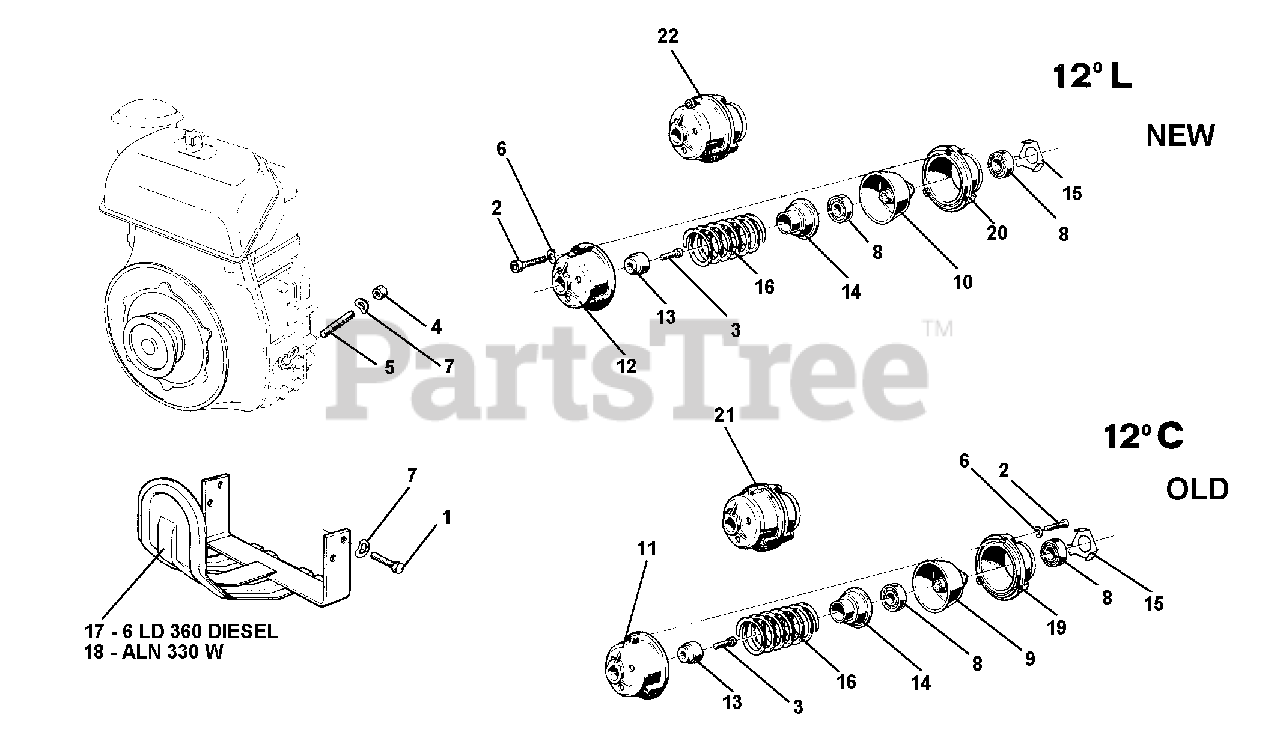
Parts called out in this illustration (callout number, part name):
1	SCREW M8 X 16
2	SCREW M6 X 35
3	SCREW TE CE M8 X 25
5	STUD M8 X 40 X 14 X 14
6	WASHER, LOCK 6.4
7	WASHER, LOCK 8.4
8	BEARING 17 X 40 X 12 6203 2RS
9	CONE, CLUTCH
10	LONG CLUTCH CONE
11	BELL, CLUTCH SPRING AL 290
12	LONG CLUTCH BELL
14	BUSH, SPRING HOLDER
15	BEARING PLATE
16	SPRING CLUTCH
17	MOTOR HOOD LDA 520 MF 715 C
18	GUARD, MOWER MOTOR PULLEY
19	CLUTCH RING
20	LONG CLUTCH RING
21	REPLACED BY ITEM 22 CLUTCH
22	FITTED LONG CLUTCH
